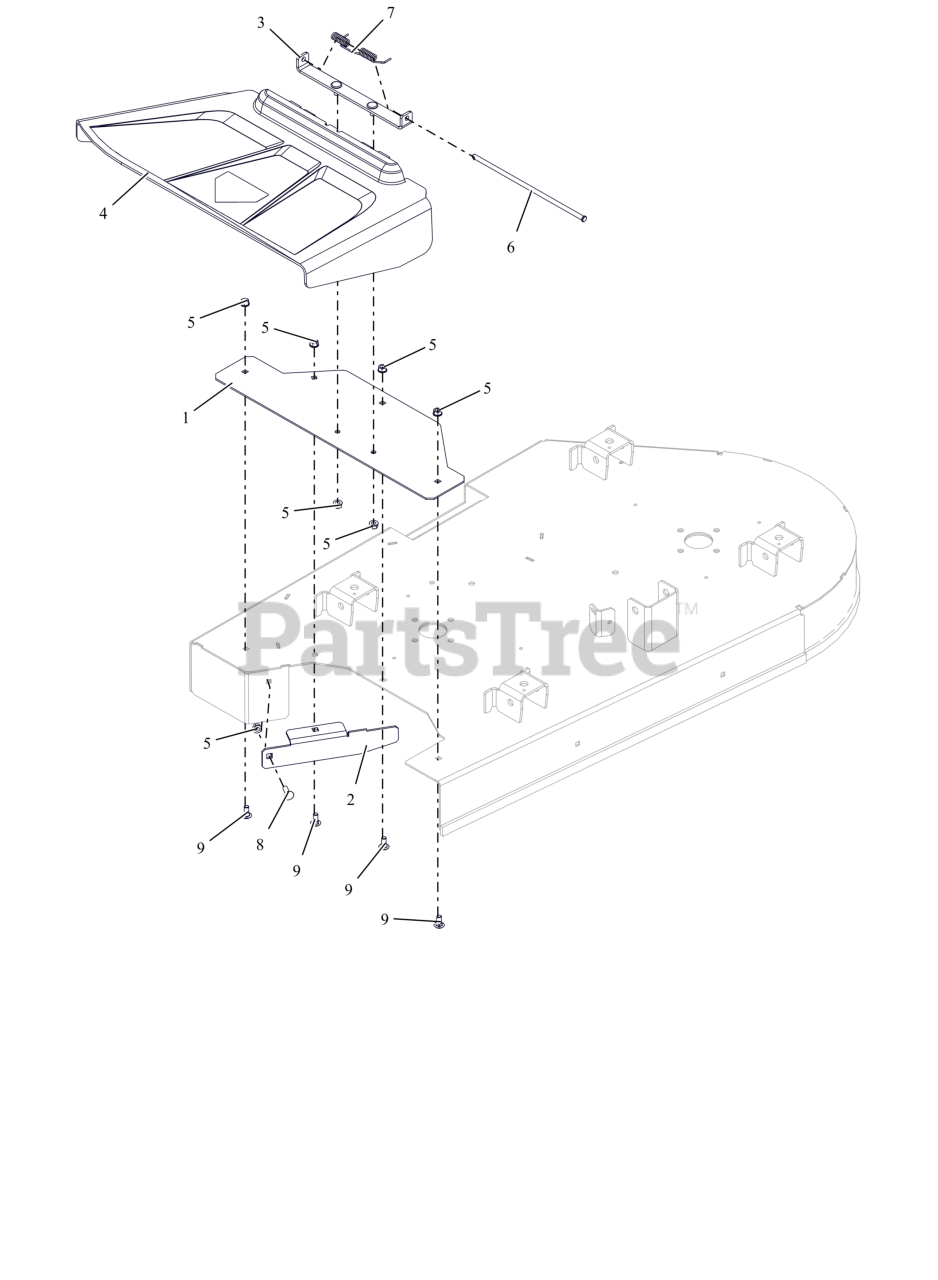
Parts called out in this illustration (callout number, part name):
1	PLATE, DECK - DISCHARGE (RED)
2	STRIP, DEFLECTOR EDGE (RED)
4	CHUTE, SIDE DISCHARGE
5	NUT,LK-CTR-FLG .31-18 GF ZCC
6	PIN, SLIC-.312X10.45
7	SPRING-TORSION
8	BLT,RHSN .31-18X1.00 G5 ZCC
9	BLT,RHSN .31-18X.75 G5 ZCC
